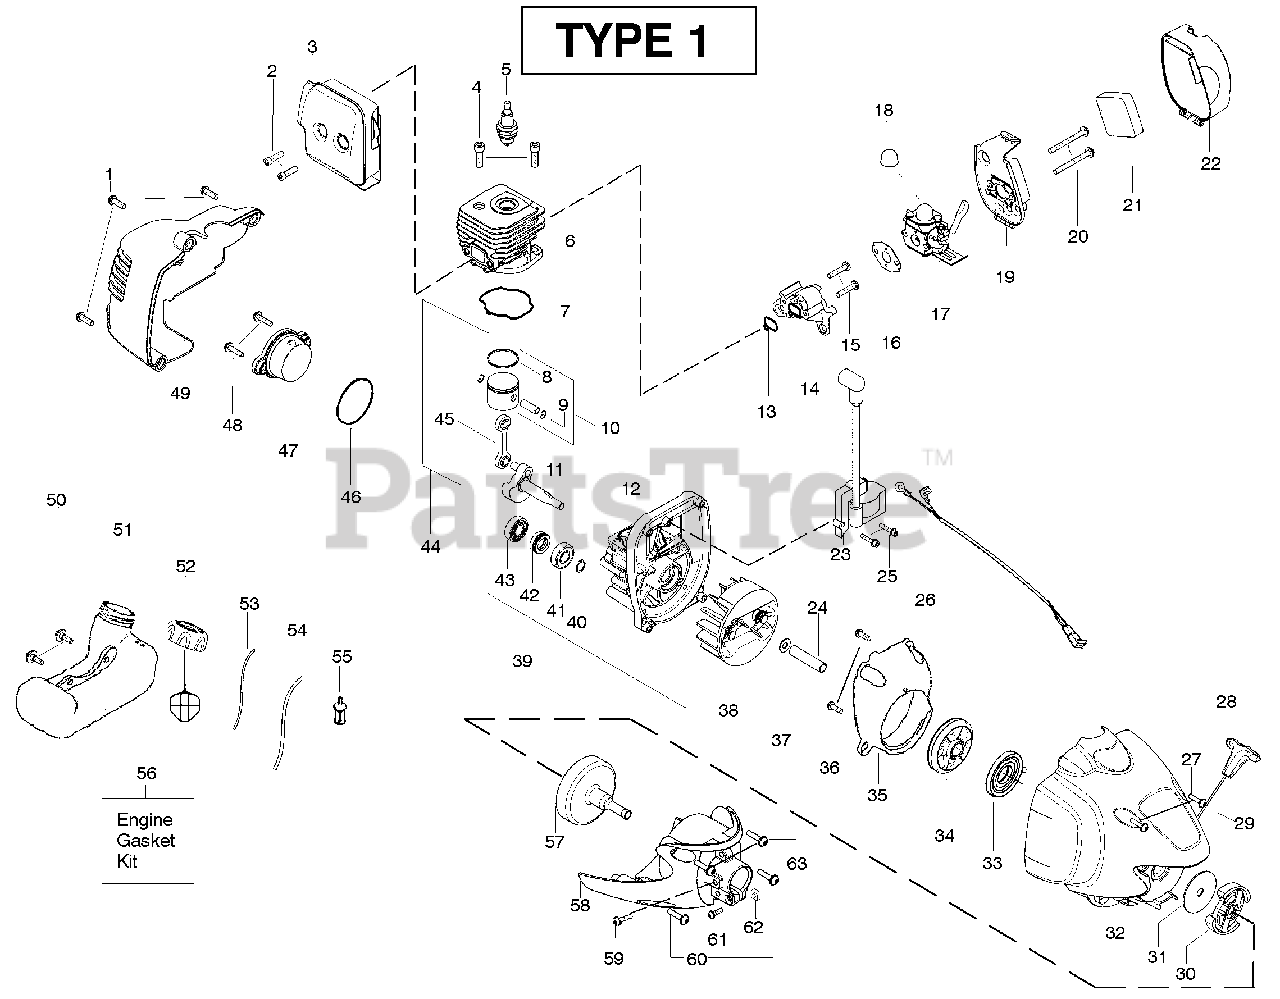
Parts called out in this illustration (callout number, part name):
2	Bolt-Muffler
3	Assy-Muffler/Shield
4	Screw-Cylinder
5	Spark Plug (RCJ 6Y)
6	Cylinder
7	Seal-Cylinder (kit)
8	Piston Ring
9	Retainer-Piston Pin
10	Kit - Piston
11	Assy-Crankshaft
12	Assy-Crankcase
13	Seal-Cyl/Carb.(kit)
14	Adapter-Carb.
16	Gasket-Carb. (kit)
17	Kit-Carb.(C1U-W19)
18	Bulb - Purge
21	Foam-Air Filter
22	Cover-Air Box
23	Ignition Module
24	Spacer-Flywheel
26	Assy-Switch wire
27	Screw
28	Handle-Starter
29	Kit - Rope
30	Assy-Clutch
31	Washer-Clutch
32	Assy.-Fan Hsg
33	Spring-Starter
34	Kit-Starter Pulley
37	Washer-Clutch Flat
38	Assy-Flywheel
39	Assy-C'case & C'shaft
40	Retain. Ring-C'shaft
41	Outer Bearing
42	Seal-C'shaft
43	Inner Bearing
44	Kit-piston/rod
45	Kit-Conn. Rod
46	O-Ring-C'case (kit)
47	Assy-Plug
49	Shroud-Rear
50	Retainer-Tank
51	Assy-Fuel Tank
52	Assy-Fuel Cap
53	Kit-Fuel Line (Small)
54	Kit-Fuel Line (Large)
55	Assy-Fuel Pickup
56	Kit-Engine Gasket
57	Assy-Clutch Drum
58	Assy-Clutch Cover
59	Screw-Align
61	Screw 12-24
62	Nut 12-24
